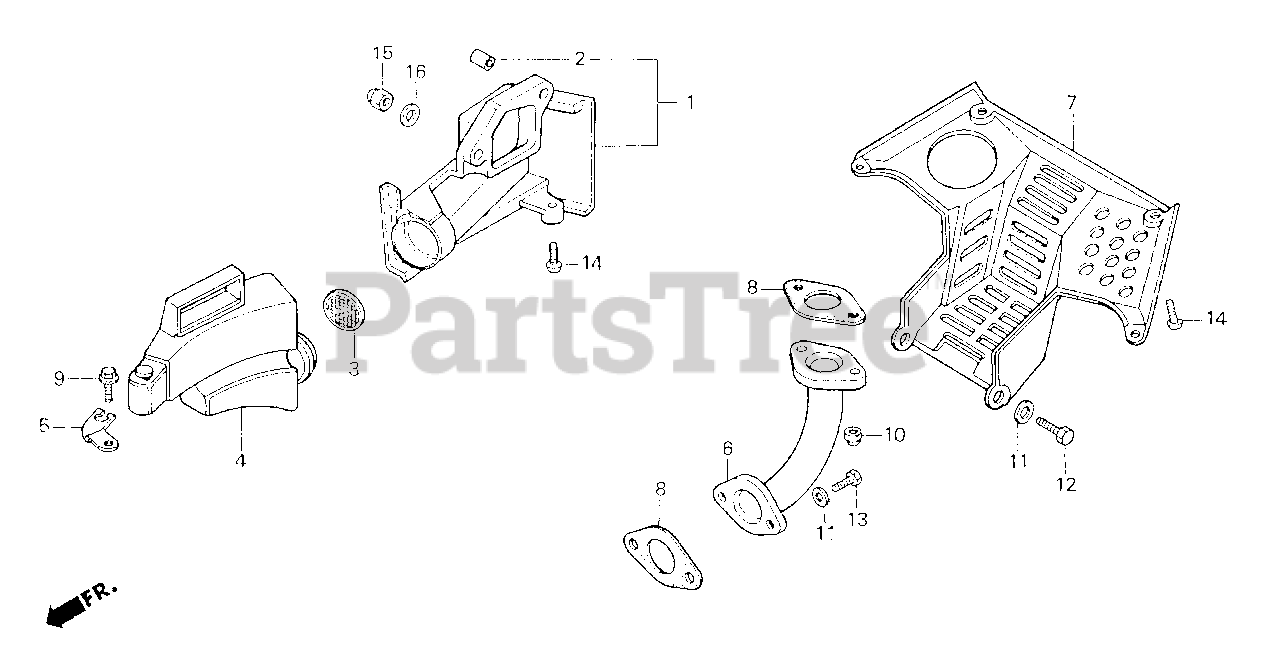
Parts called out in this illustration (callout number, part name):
1	GUIDE, AIR
2	COLLAR, DISTANCE
3	TRAP, FLAME
4	CHAMBER, AIR GUIDE
5	STAY, AIR GUIDE CHAMBER
7	PROTECTOR, EX. PIPE
8	GASKET A, EX. PIPE
9	BOLT, FLANGE (6X18)
10	NUT, CAP (6MM)
11	WASHER, PLAIN (6MM)
12	BOLT, HEX. (6X12)
13	BOLT, HEX. (6X16)
14	SCREW, TAPPING (5X16)
15	NUT, CAP (5MM)
16	WASHER, PLAIN (5MM)
